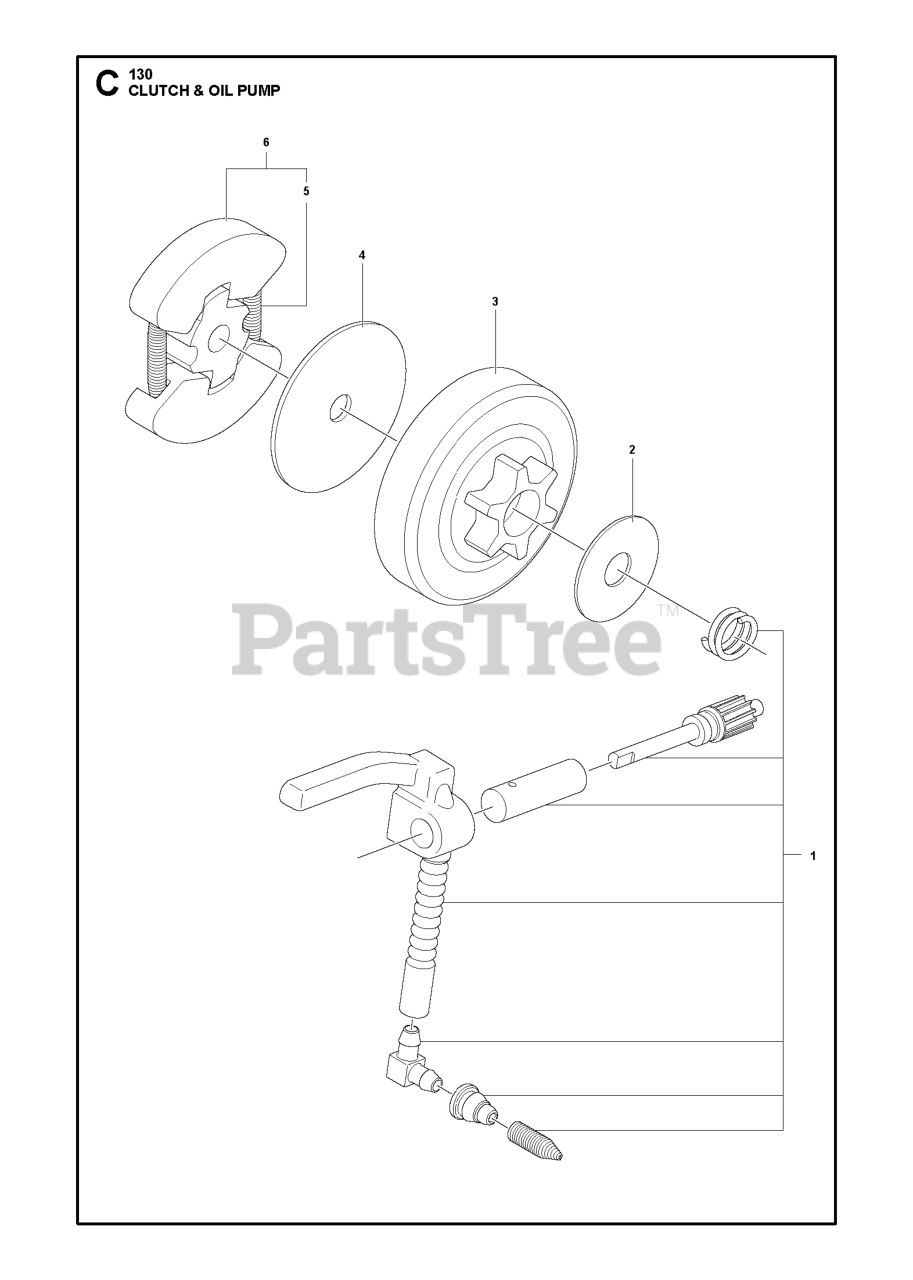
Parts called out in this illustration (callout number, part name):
1	SERVICE KIT OIL PUMP
3	CLUTCH DRUM ASSY
4	FRICTION DISC,CLUTCH 36/41
5	CLUTCH SPRING 36/41
6	CLUTCH ASSEMBLY
